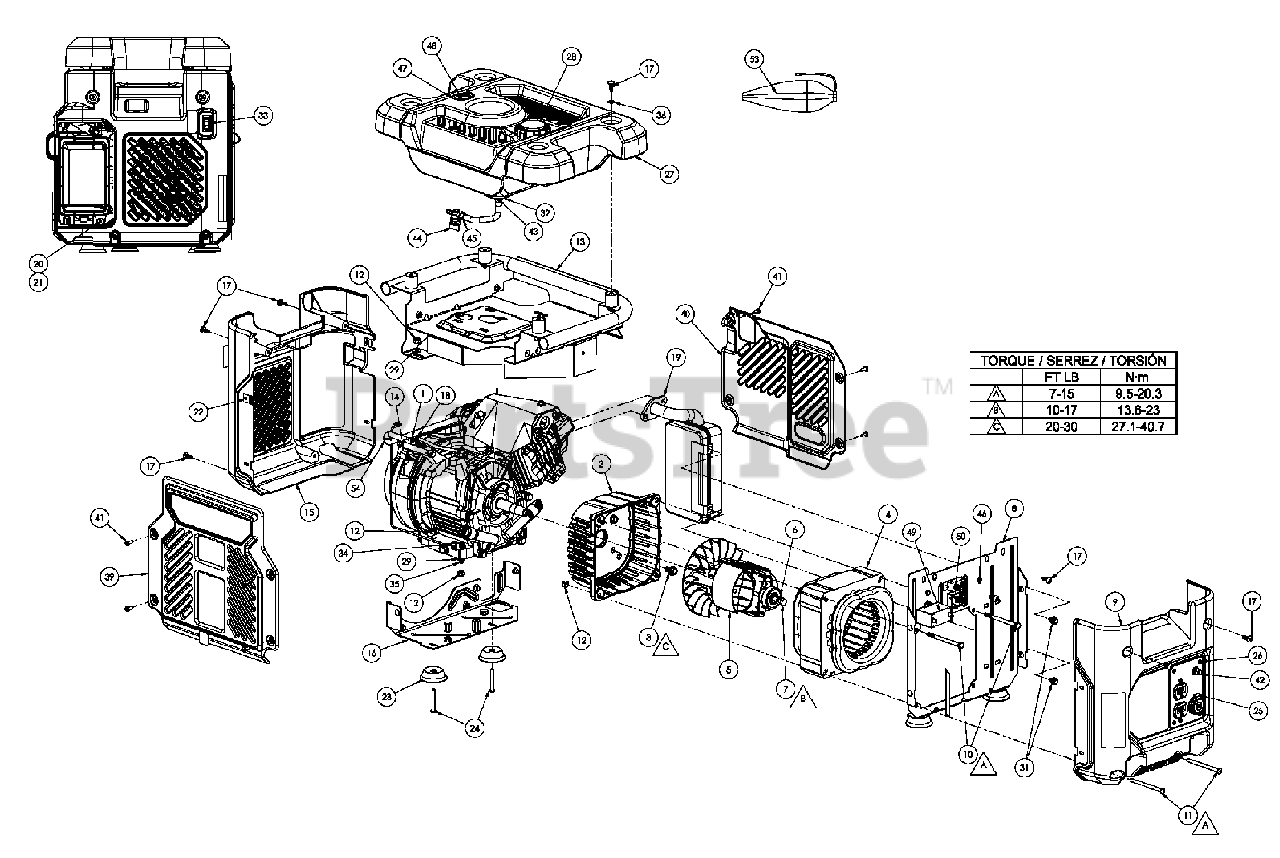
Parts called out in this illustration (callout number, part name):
1	Engine Subaru
2	Engine Adapter
3	Bolt Whz 5/16-24 x 5/8
7	Bolt, Rotor 5/16-24 x 5-3/4
8	Assy, Stator Bracket
11	Screw, Torx T30 1/4-20 x 3.50
12	Nut, Nyloc 1/4-20
13	Assembly, handle bracket
15	Panel, recoil
16	Bracket, recoil
17	Screw, Torx T30 1/4-20 x .63
18	Washer, fender
21	Screw, Torx T30 1/4-20 x 1.25
22	Clip
23	Foot, Rubber 106-W
24	Screw, Torx T30 1/4-20 x 1.50
25	Panel, wired
26	Screw #6-19 x .50
27	Assy, Fuel Tank
28	Cap, Fuel
31	Bolt, Whz 1/4-20 x 3/8
32	Fuel bushing
33	Switch, rocker
34	Lug, Ground
36	Washer Nylon .25 ID
39	Panel Side Cover
40	Shield, Muffler
41	Screw, Torx T20 #10-24 x .50
42	Circuit Breaker, 20A
43	Fuel Filter
44	Fuel Shut Off, Inline
45	Clamp, Hose 1/2"
46	Screw CRPH #10-24 x .50
47	Bushing, breather
48	Assembly, duck bill fuel valve
49	Capacitor
50	Bridge Diode
53	Assembly, Battery Cable
54	Assembly, Fuel line
